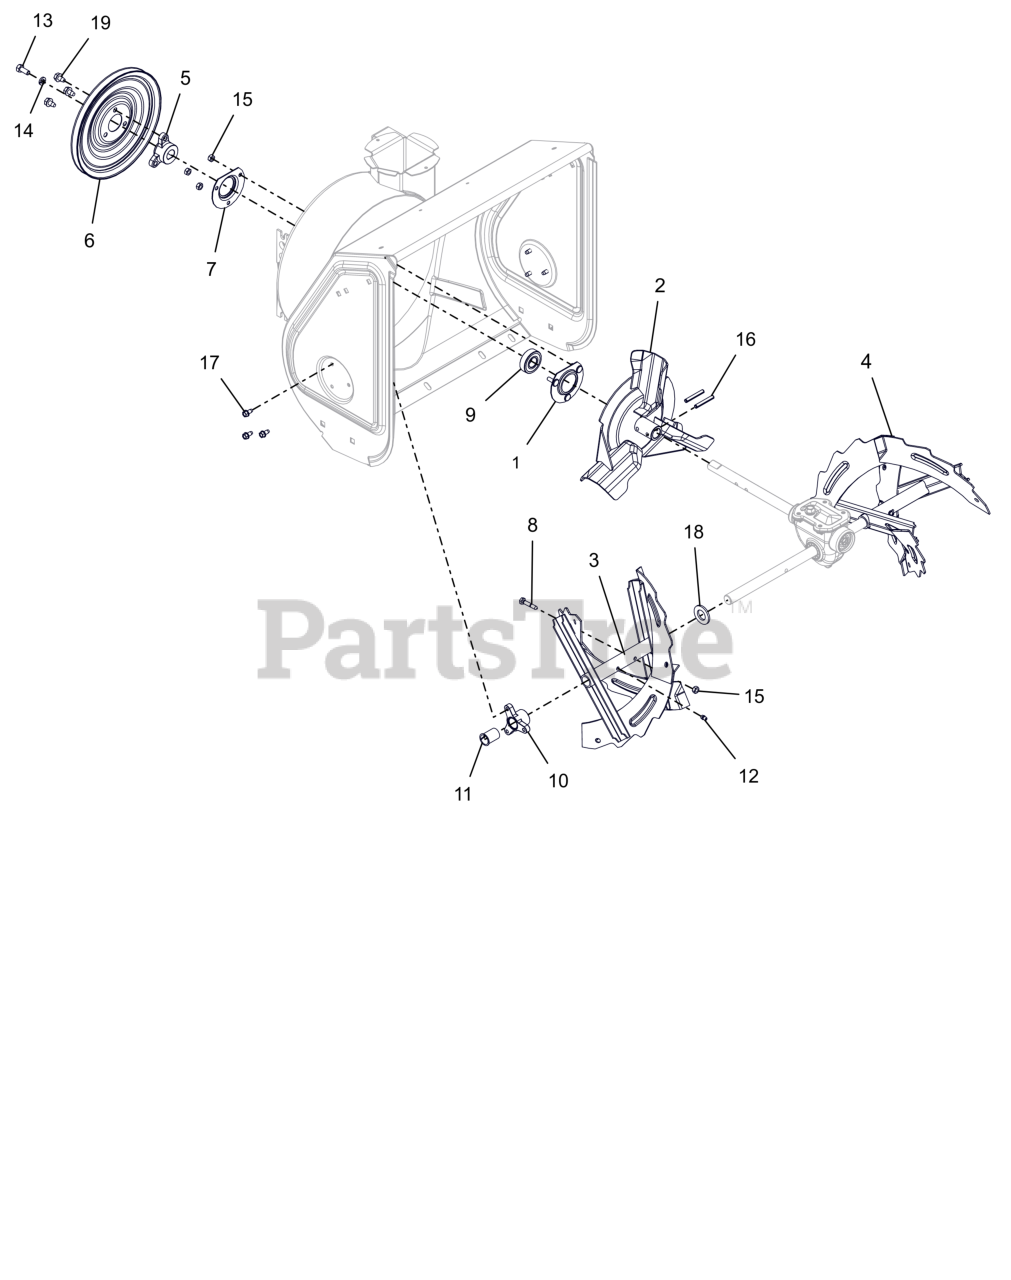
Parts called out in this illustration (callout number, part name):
1	BEARING FLANGE
2	IMPELLER, COMPACT 12" 3-BLADE
3	AUGER, 20" RH, BLK SERR W/ZERK
4	AUGER, LH 20", BLK SERR W/ZERK
5	PULLEY HUB, BOLT-ON D-BORE .75
6	PULLEY,SPIN FORM SINGLE GROOVE
7	BEARING FLANGE
8	SHEAR BOLT
9	BRG-BALL .750X1.750X.50
10	BUSHING, RAKE SHAFT .75"
11	BSHG-FLG SPLIT NYLINER .75"ID
12	ZERK,FITTING .25X.125 DRIVE IN
13	BLT, HEX .31-24X.750 G5 ZCC
14	WSHR, LK-HVY .312X.097 ZCC
15	NUT,LK-CTR .25-20 GA ZCC
16	PIN-ROLL .250X1.75
17	SCR-TAP .25-20X.50 HWH ZCC
18	WSHR, FLT .812X1.469X.134 ZCC
19	SCR,TAP .312-18X.50 HWH TR ZCC
